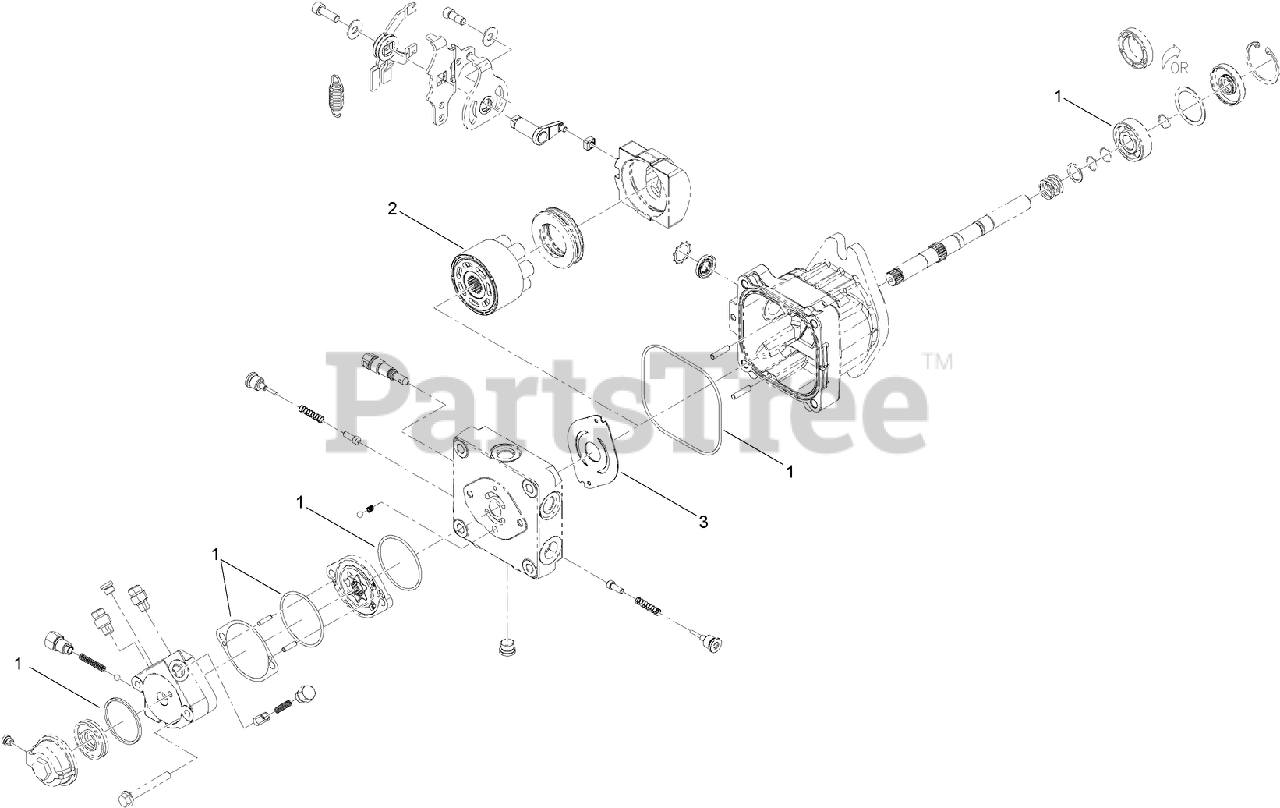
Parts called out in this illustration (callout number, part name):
1	OVERHAUL SEAL KIT
2	CYLINDER BLOCK KIT
3	PLATE-VALVE
